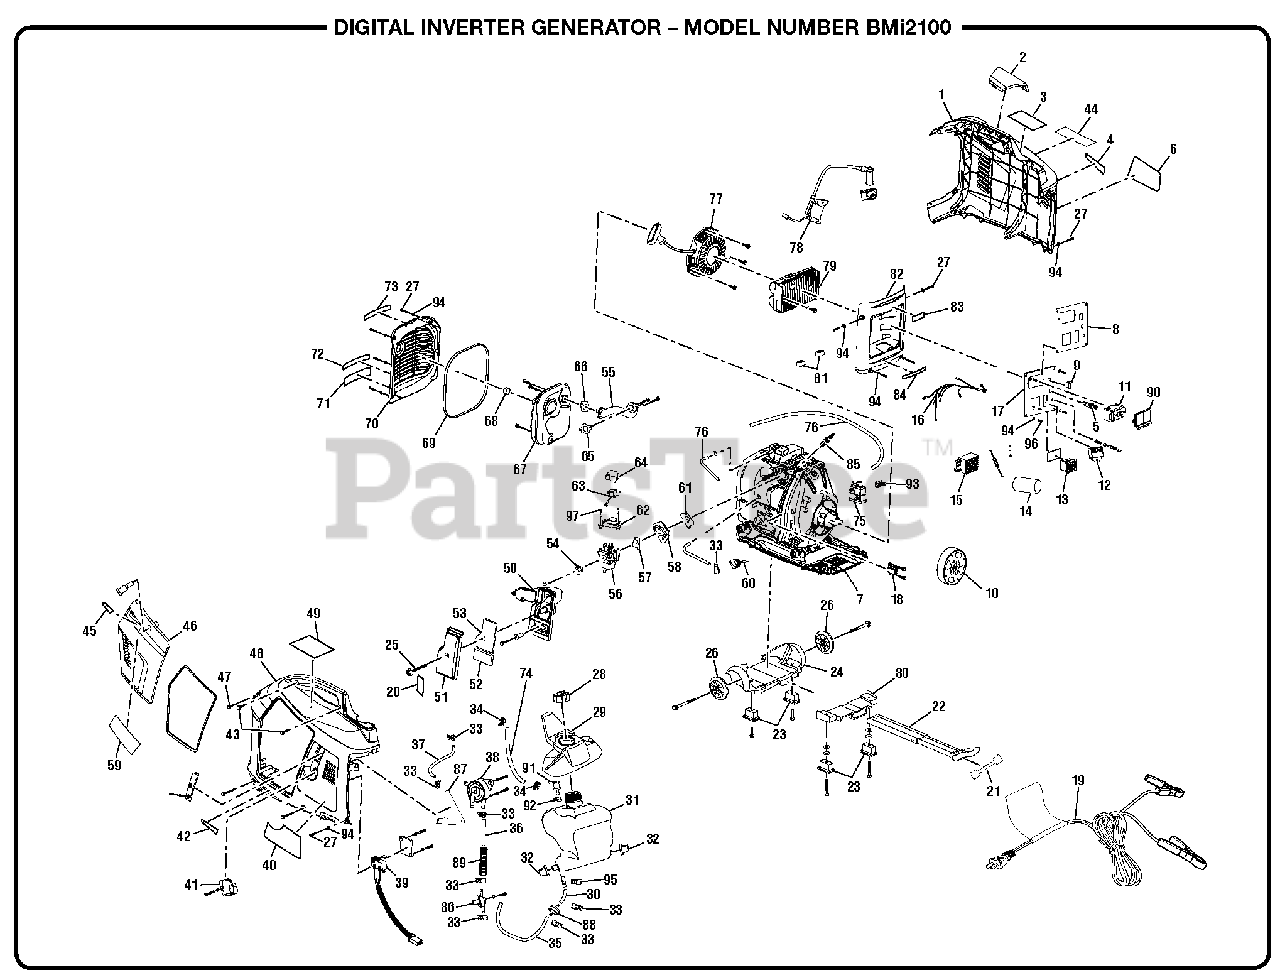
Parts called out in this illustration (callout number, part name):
1	Right Housing
2	Spark Plug Access Cover
3	E85 Label
4	Fire Danger Label
5	Reset Button
6	Features Label
8	Control Panel Label
9	Auto Idle Switch
10	Stator Assembly
11	AC Receptacle (120 Volt)
12	Ignition Module
13	DC Receptacle
14	Heat Shrink Tube
15	Bridge Rectifier
16	Wiring Harness (Internal)
17	Control Panel
18	Pick-Up Coil
19	Battery Charging Cable
20	Oil Warning Label
21	Handle Release Label
22	Handle Assembly
23	Rubber Foot
24	Rear Handle and Wheel Bracket
27	Screw (M5 x 15 mm)
28	Fuel Cap Assembly
29	Fuel Overspill Guard
30	Fuel Line (Tank to Filter, 6 mm x 10 mm)
31	Fuel Tank
32	Fuel Tank Support
33	Clamp (D9 x 1.2 mm)
34	Clamp (D7 x 0.8 mm)
35	Fuel Line (Filter to Valve, 6 mm x 10 mm)
36	Fuel Line (Valve to Pump, 6 mm x 10 mm)
37	Fuel Line (Pump to Carburetor, 6 mm x 10 mm)
38	Fuel Pump
39	Engine Shut Off Switch
40	Quick Start Label
41	Switch Handle
42	Lubricant Label
43	Bolt (M6 x 30 mm)
44	Logo Label (Right)
45	Choke Label
46	Maintenance Cover
47	Bolt (M6 x 100 mm)
48	Left Housing
49	CPSC Label
50	Air Filter Back
51	Air Filter Cover
52	Air Filter (Lower)
53	Air Filter (Upper)
54	Intake Gasket
55	Exhaust Pipe
56	Carburetor Assembly
57	Carburetor Gasket
58	Intake Seat
59	Logo Label (Left)
61	Insulator Gasket
62	Governor Bottom Cover
64	Governor Top Cover
65	Manifold Gasket
66	Muffler Gasket
68	Spark Arrestor
69	Muffler Cover Seal
70	Muffler Cover
71	Data Label
72	Combustion Label
73	Hot Surface Label
74	Vent Hose (Tank to Carbon Canister)
75	Carbon Canister
76	Vent Hose (Carbon Canister to Air-box)
77	Recoil Starter Assembly
78	Ignition Coil
79	Inverter Module
80	Foot Brace (Front Handle)
81	Inverter Module Support
82	Control Panel Holder
83	Logo Label (Small)
84	Ground Warning Label
85	Spark Plug
86	Fuel Shut Off Valve
87	Fuel Pump Bracket
88	Fuel Filter
89	Fuel Line Spring
90	Receptacle Cover
91	Fuel Tank Vent Valve
93	Clip (D9 x 1.2 mm)
94	Flat Washer (ID5.3 x OD10)
95	Clamp (D10 x 0.8 mm)
96	Screw (M4.8×16 mm)
97	Screw (M3 x 5 mm)
